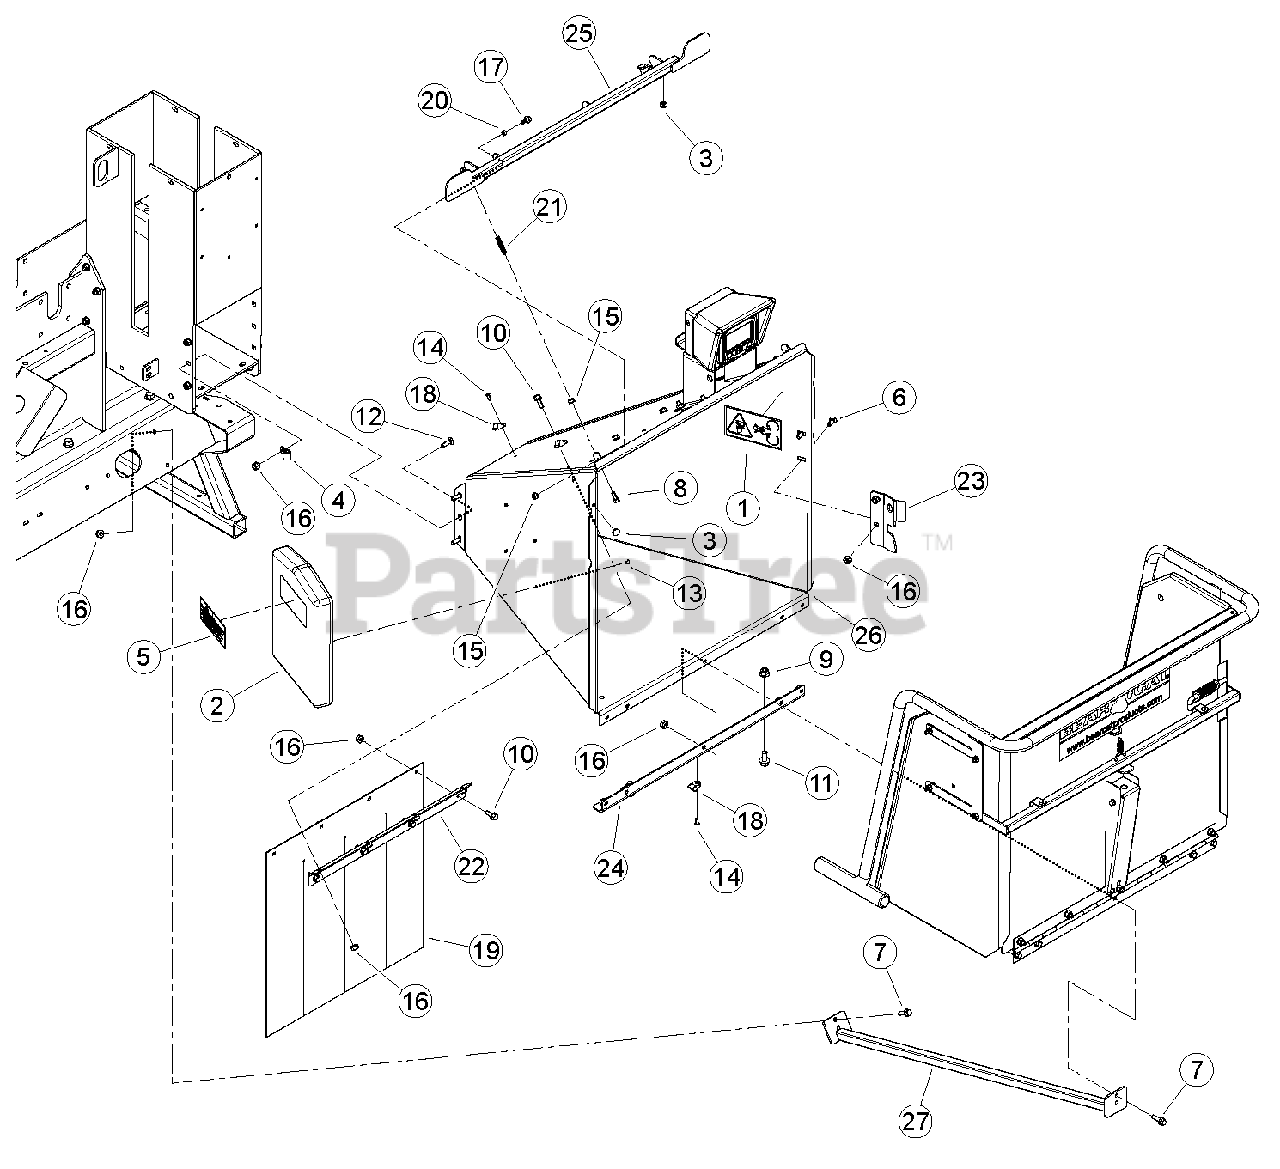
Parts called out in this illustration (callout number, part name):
1	DECAL, BLADE DANGER ISO
2	CONTAINER, INSTR. MANUAL
3	BUMPER, RUBBER
4	CLAMP, 9/16 COATED
5	DECAL, MUTILINGUAL MANUAL
6	BOLT, 3/8 X 1" GR5 CRG NC ZP
7	BOLT, 3/8 X 1-1/4 FLANGE NC
8	BOLT, 5/16 X 3/4 FLANGE NC
9	NUT, 1/2-13 NYLOCK FLANGE
10	BOLT, 3/8 X 1 FLANGE NC
11	BOLT, 1/2-13 1.00 GR5 FLANGE NC
12	BOLT, 3/8 X 1-1/4" GR5 CRG NC ZP
13	RIVET, AL BLIND 1/4 X 1/2 DOME HEAD
14	RIVET, AL BLIND 1/4 X 3/4 DOME HEAD
15	NUT, 5/16-18 NYLOCK-FLANGE
16	NUT, 3/8-16 NYLOCK FLANGE
17	BOLT, 5/16-18 X 3/4 ZP FLANGE SHOULDER
18	CLAMP, CABLE MOUNT
19	FLAP, 9 INCH CHUTE
20	BEARING, .375 X .50 X .25 LONG
21	SPRING, COMPRESSION .437 DIA X 2.0 LONG
22	SUPPORT, 9 INCH CHIPPER FLAP
23	PLATE, TRAY LATCH
24	ANGLE, INFEED SUPPORT
25	WELDMENT, 8/9" TOP SAFETY BAR
26	WELDMENT, BIG CHIPPER CHUTE
27	WELDMENT, CHUTE SUPPORT
